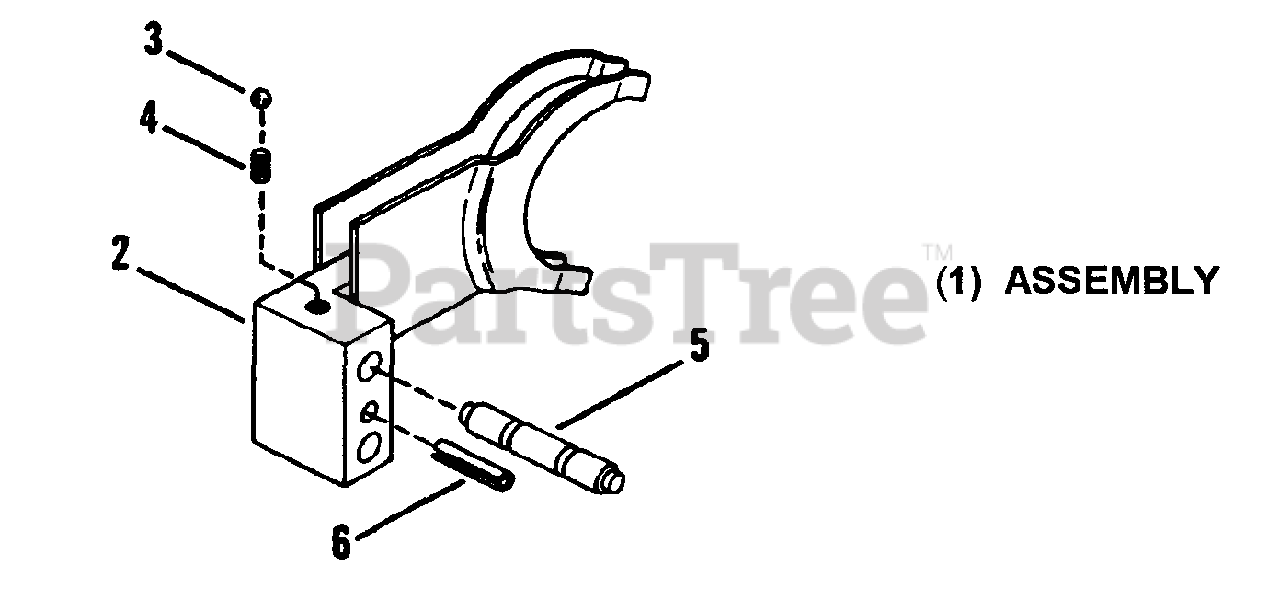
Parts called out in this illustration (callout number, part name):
1	ASSEMBLY, HI-LO SHIFTER
2	FORK, Shift
3	BALL, Detent
4	SPRING, Detent Ball
5	GUIDE-PIN, Detent
6	ROLL-PIN, 1/4 x 1-1/4"
